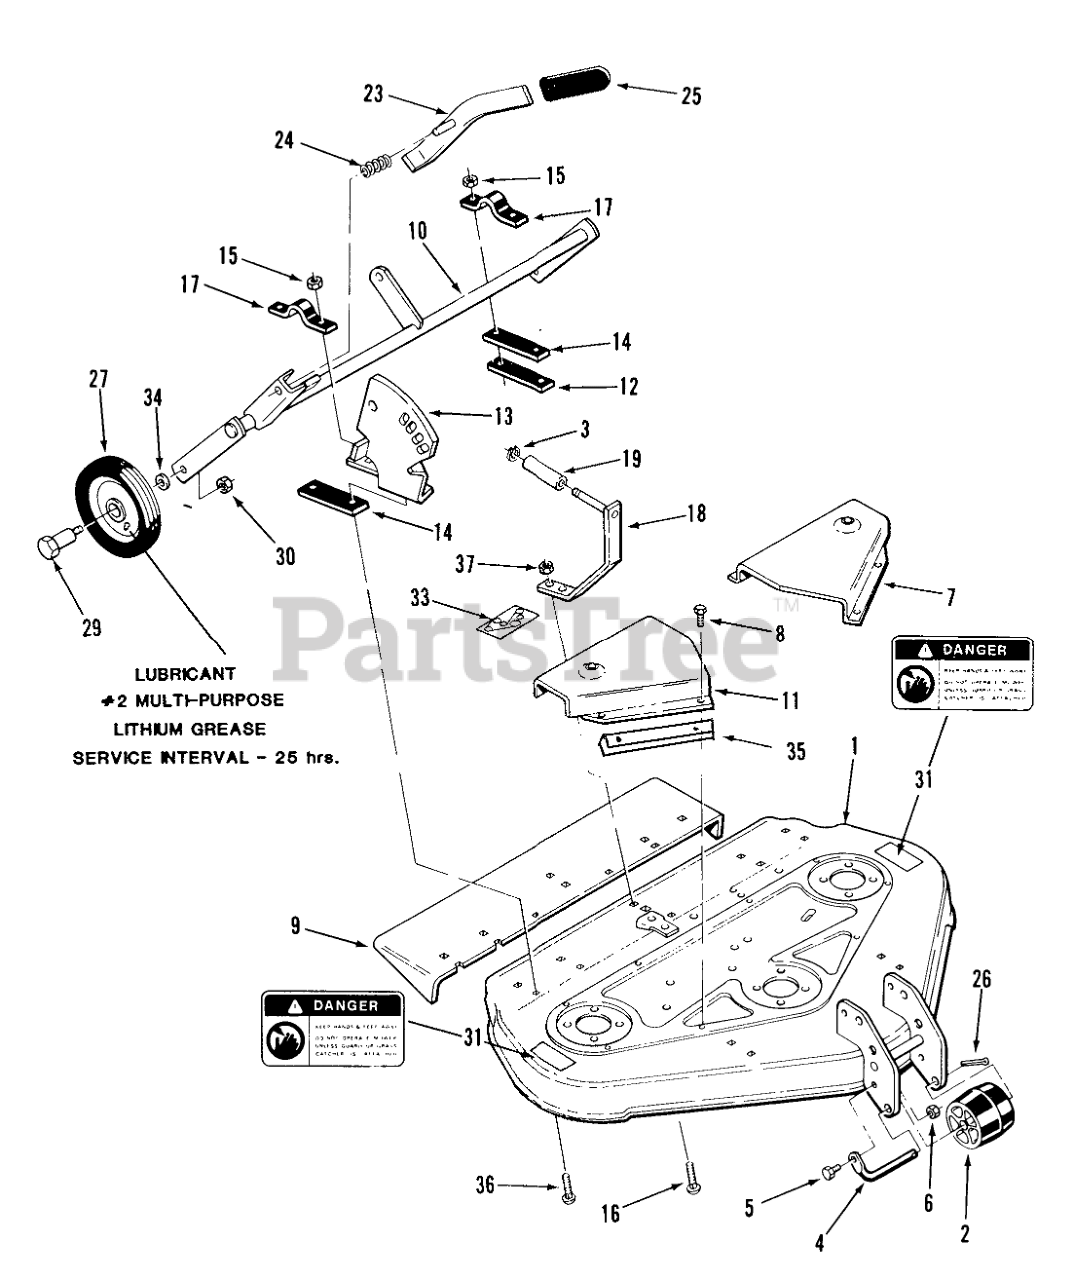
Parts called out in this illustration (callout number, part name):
1	X-REF 17-2229
2	ROLLER ASSY
3	Snap Ring
4	ROLLER-SHAFT
5	H H C S
6	Nut
7	Cover-Belt
8	SCREW -4
9	Chute Extension
10	ASSY GAGE WHEEL S R
11	Belt Cover RH
12	Bar
13	QUADRANT R
14	STRAP 1/16 B
15	Nut
16	Bolt-Carriage
18	ASSY BRACKET GUID R
19	SPACER
23	Lever
24	SPRING-COMPRESSION
26	Cotter Pin
27	WHEEL ASM
29	BOLT-SHOULDER
30	Nut
31	Danger Decal
33	DECAL-HEIGHT BELT
34	WASHER
35	BAR R
36	Bolt
37	NUT
